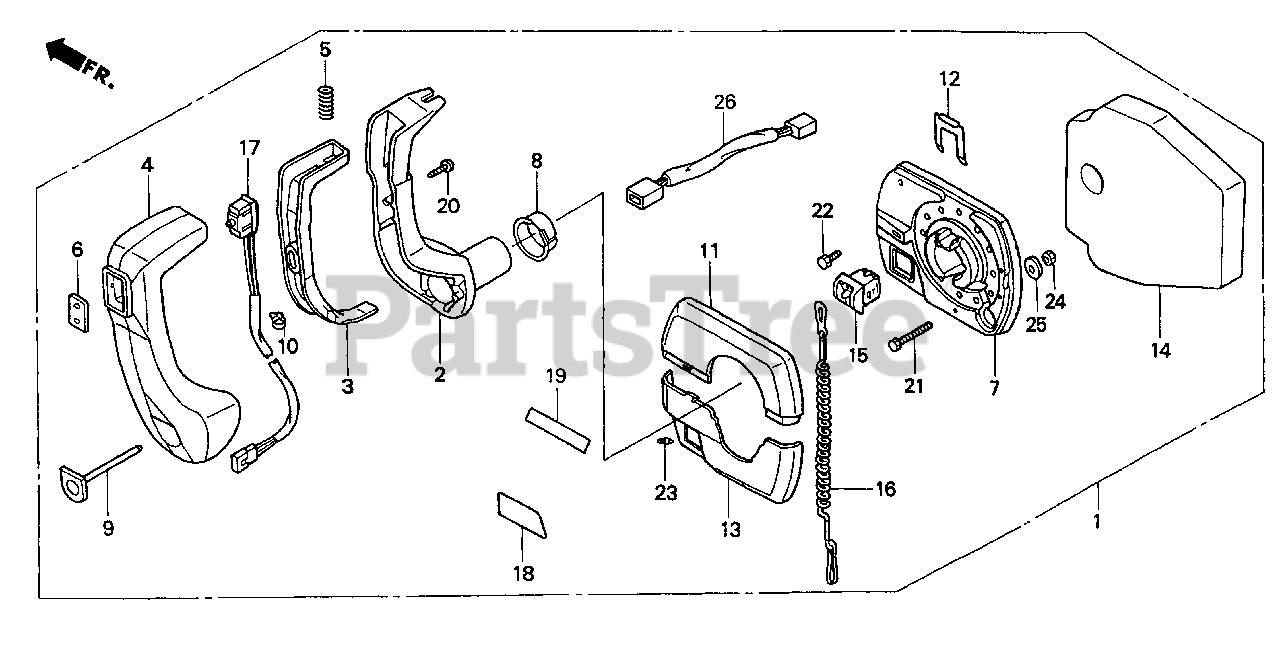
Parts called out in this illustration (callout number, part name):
1	BOX ASSY., REMOTE CONTROL
2	HANDLE, REMOTE CONTROL
3	LEVER, HANDLE LOCK
4	GRIP, REMOTE CONTROL HANDLE
5	SPRING, REMOTE CONTROL HANDLE
6	COVER, GRIP
7	HOUSING ASSY., REMOTE CONTROL
9	BUTTON, THROTTLE
10	BAND B, CABLE
11	HOUSING, REMOTE CONTROL BOX
13	HOUSING, REMOTE CONTROL BOX
14	HOUSING ASSY. (INNER)
15	SWITCH ASSY., EMERGENCY STOP
16	WIRE, EMERGENCY
17	SWITCH ASSY., POWER TRIM-TILT
18	MARK, REMOTE CONTROL
19	MARK, REMOTE CONTROL
23	SCREW SET (1/4-20X16")
24	NUT (1/4X20)
26	HARNESS ASSY., POWER TRIM-TILT Use from Frame SN 1000621.
